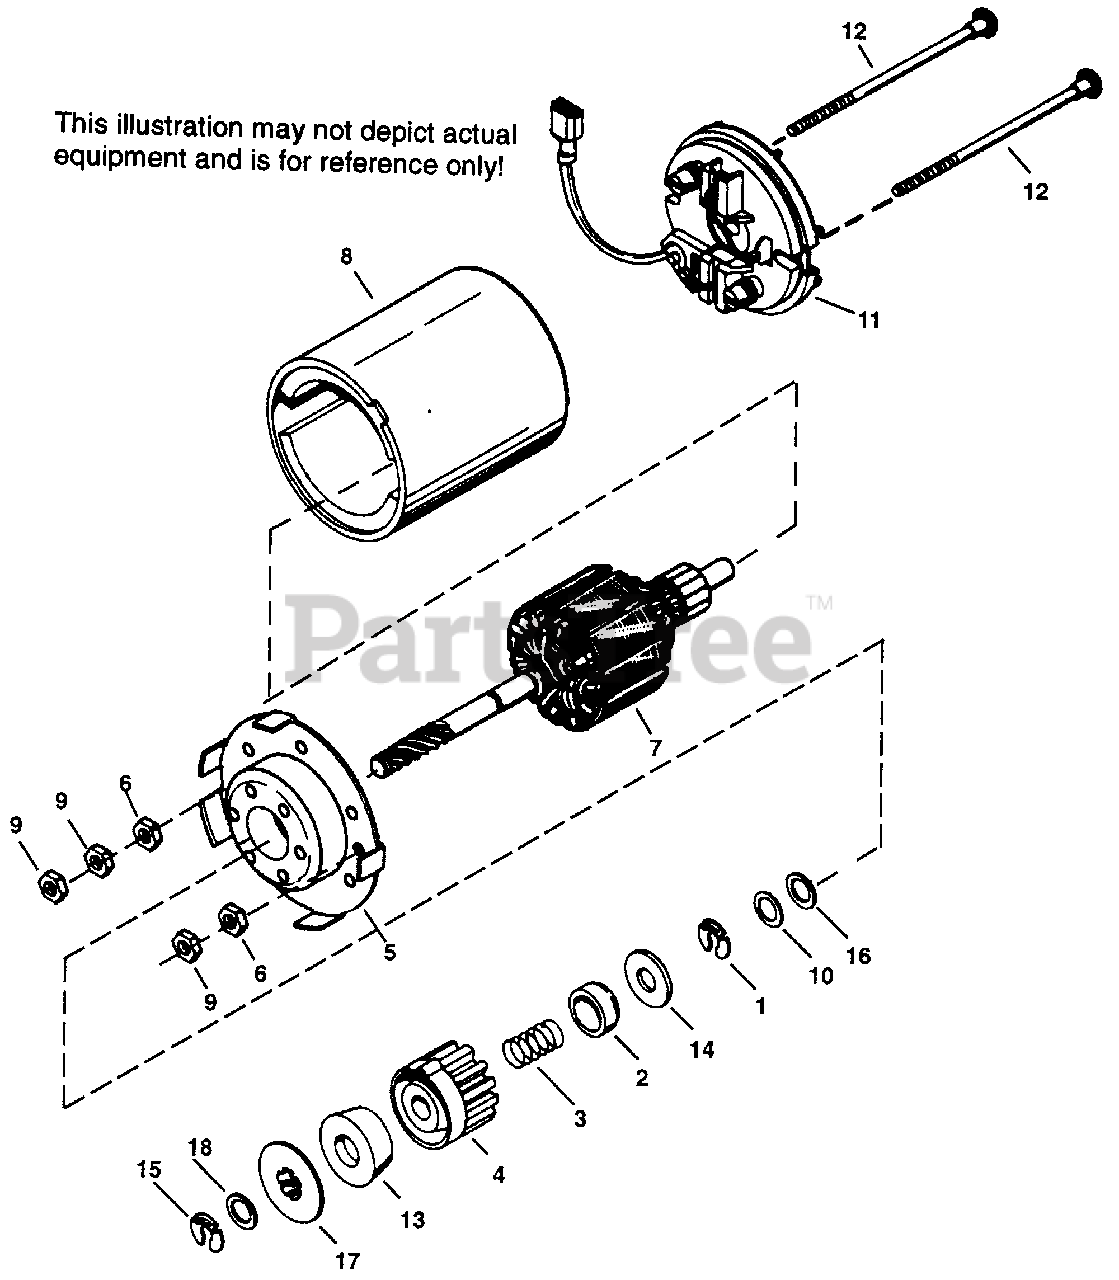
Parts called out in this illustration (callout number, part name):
1	Retainer Ring
2	Spring Retainer
3	Spring
5	Drive End Cap Ass'y.
6	Lock Nut
7	Armature
8	Housing Ass'y.
10	Thrust Washer
11	Commutator End Cap Ass'y. Incl. brush es
12	Bolt, 10-32 x 3-19/32"
13	Pinion Driver
14	Cup Washer
15	Retainer Ring
17	Drive Nut
18	Dust Washer
